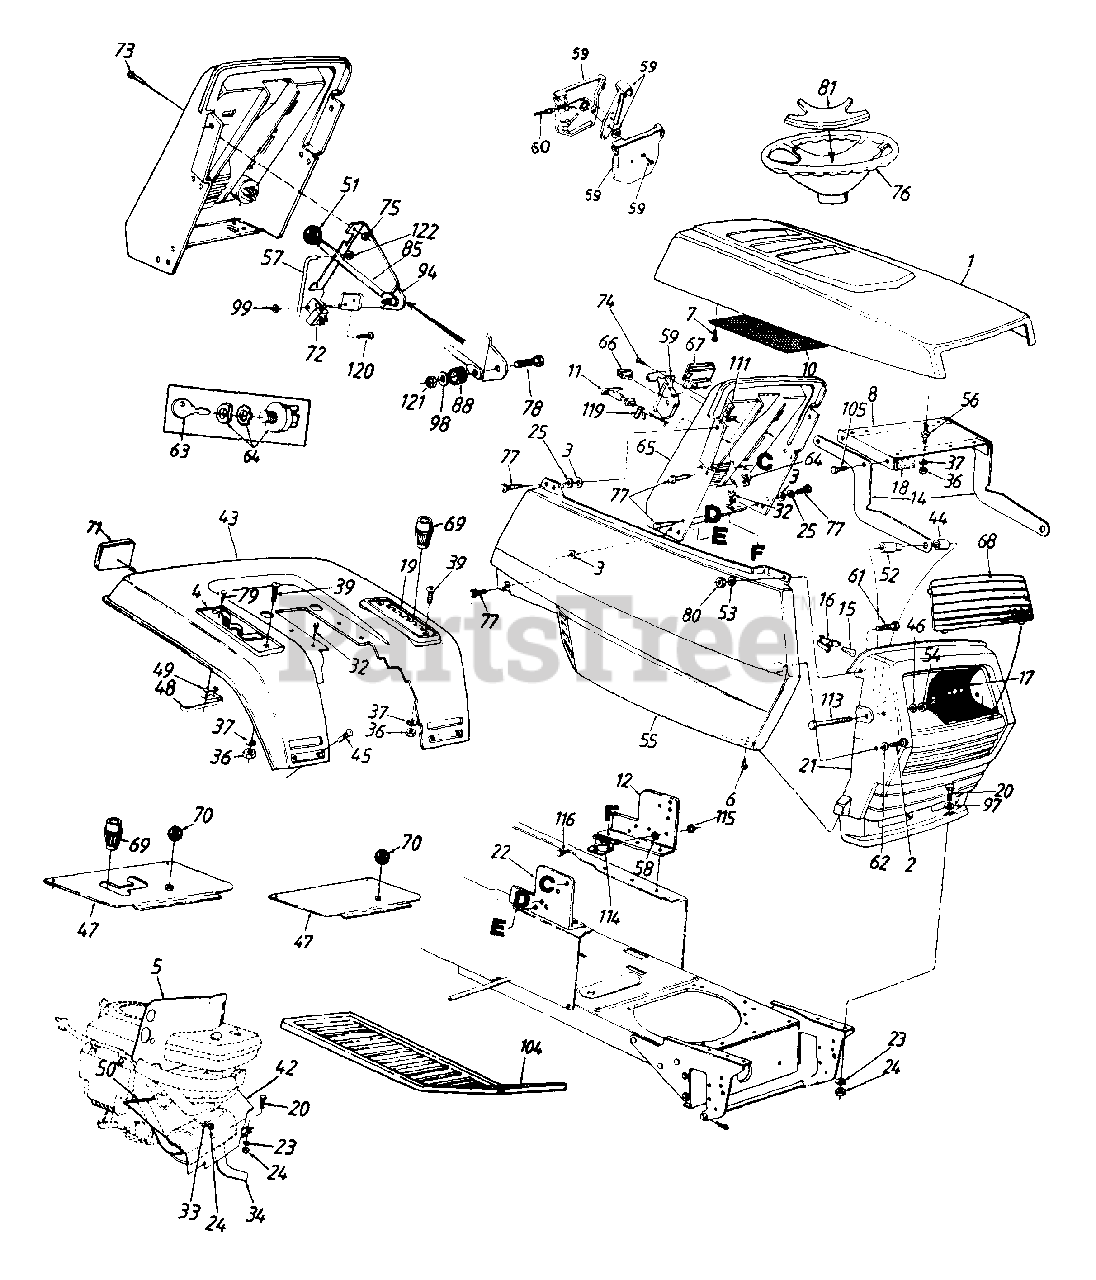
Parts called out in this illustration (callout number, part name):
3	Bolt Retainer 1/4" I.D.
4	Forward/Reverse Index Brkt.
5	Heat Shield
6	Truss Mach. B-Tap Scr. #10 x .5" Lg.
7	Hex Wash Hd. AB-Tap Scr. #8 x .5" Lg.
11	Choke Control
15	Lamp
16	Twist Lock - Lamp Socket
17	Reflector - Headlight
18	Foam Seal
19	Speed Control Index Brkt.
20	Hex Bolt 5/16-18 x .75" Lg.
22	Dash Support Bracket - R.H.
23	L-Wash. 5/16" I.D.
24	Hex Nut 5/16-18 Thd.
25	Fl-Wash. 1/4" I.D. x .93" O.D.
32	Hex Wash. Hd. AB-Tap Scr. 5/16 x .75" Lg.
33	L-Wash. 5/16" I.D.
34	Muffler
36	Hex Nut 1/4-20 Thd.
37	L-Wash. 1/4" I.D.
39	Truss Mach. Scr. 1/4-20 x .75"
42	Front Heat Shield
45	Carriage Bolt 1/4-20 x .50" Lg.
46	Fl-Wash..328" I.D. x.68" O.D.
47	Transmission Panel
48	Reverse Safety Switch
49	Insulator Nut Plate
50	Trim Strip 12" Lg.
51	Knob
52	Shld. Spacer .33" I.D.
53	Fl-Wash..281" I.D. x .5" O.D.
54	Hex Cent. L-Nut 5/16-18 Thd.
55	Side Cover Ass'y.- R.H.
56	Double Ended Stud 1/4-20 Thd.
57	Deck Control Rod
58	Ext. L-Wash. 1/4" I.D.
59	Throttle Control Box Ass'y.
60	Throttle Control Wire 35" Lg.
61	Hex Bolt 1/4-20 x .62" Lg.
62	Fl-Wash..281" I.D. x .73" O.D.
63	Ignition Key
64	Ignition Switch
65	Dash Panel
66	Light Switch
67	Ammeter
68	Lens (White Logo)
69	Shift Knob
70	Ball Knob Brake
71	Reflector
72	Safety Switch
73	Truss Mach. Scr. 1/4-20 x .5" Lg.
74	Truss Mach. AB-Tap Scr. #10 x .5" Lg.
75	Hex Sems Nut 1/4-20 Thd.
76	Steering Wheel
77	Hex Wash. Hd. Tap Scr. 1/4 x .75" Lg.
78	Hex Bolt 1/4-20 x 1.25" Lg.
79	Hex Wash. Hd. AB-Tap Scr. #8 x .50" Lg.
80	Hex L-Nut 1/4-20 Thd.
81	Steering Wheel Cap
85	Blade Clutch Lever
88	Rubber Washer
94	Deck Clutch Control Brkt.
97	Fl-Wash..344" I.D.
98	Fl-Wash..281" I.D. x .73"
99	Hex Nut #10-24 Thd.
104	Foot Pad
105	Hex Tap Scr. 1/4-20 x .5" Lg.
111	Speed Nut 1/4-20 Thd.
113	Hex Bolt 5/16-18 x 2.75"
114	Solenoid
115	Hex Sems Nut 1/4-20 Thd.
116	Hex Bolt 1/4-20 x .5" Lg.
119	Retainer Clip
120	Truss Mach. Scr. #10-24 x .5"
121	Hex Ins. L-Nut 1/4-20 Thd.
122	Push Nut 1/4" O.D. Rod
